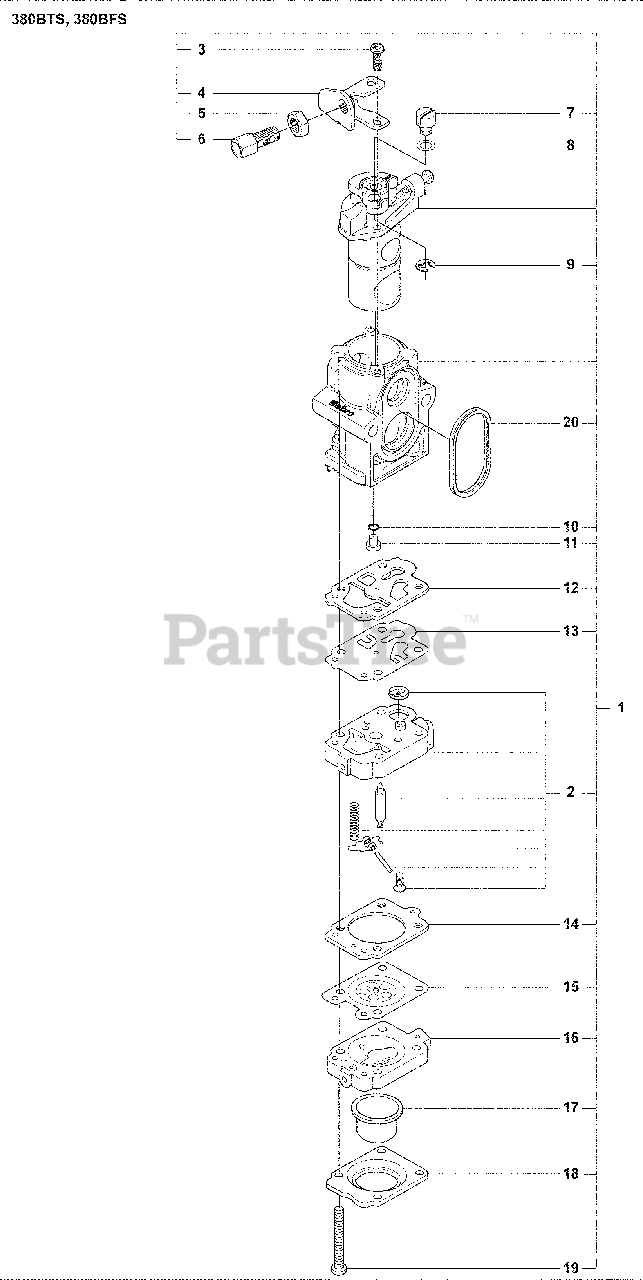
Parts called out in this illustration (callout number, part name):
1	Carburetor Assembly
2	Pump Body, A
3	Screw
5	Nut
6	Screw
7	Swivel
8	Washer
10	O-Ring
12	Gasket
13	Diaphragm
14	Gasket
15	Diaphragm
16	Diaphragm
17	Primer Blub
18	Cover
19	Screw
20	Ring
